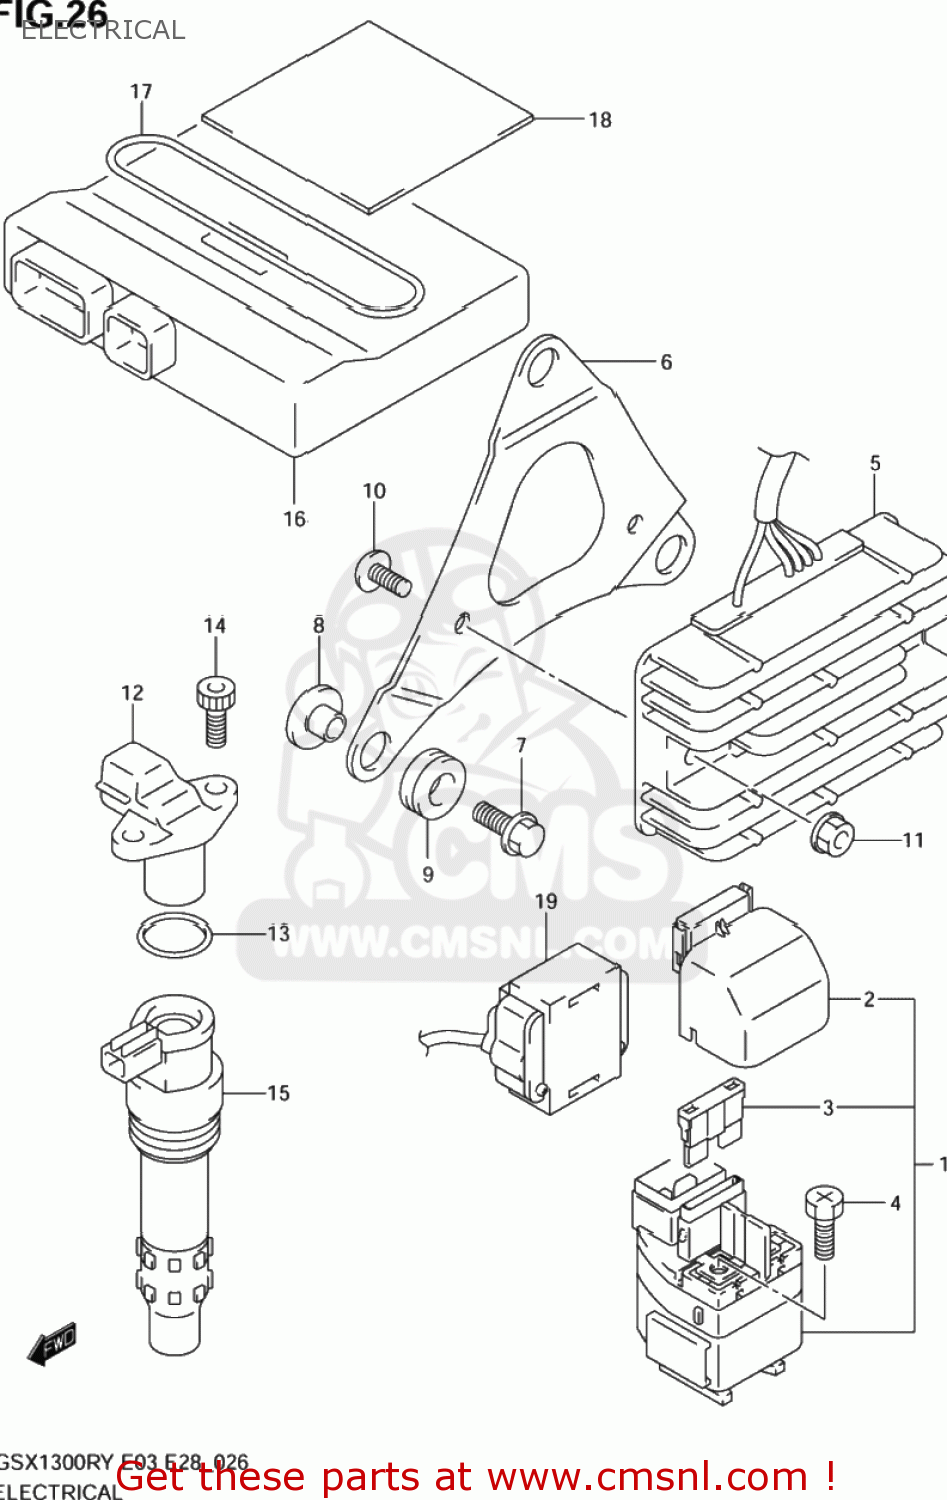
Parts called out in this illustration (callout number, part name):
1	RELAY ASSY,STARTING MOTOR
2	COVER,STARTER RELAY
3	FUSE(30A)
4	SCREW(6X8)
5	RECTIFIER ASY
6	BRACKET,RECTIFIER
7	BOLT(6X25)
8	WASHER
9	CUSHION
10	SCREW
11	NUT
12	SENSOR ASSY,CAM POSITION
13	PACKING (NAS)
14	BOLT,OIL FILLE
15	COIL ASSY,IGNITION
16	CONTROL UNIT,FI
17	BAND,BATTERY
18	PROTECTOR(40X40X16)
19	SENSOR ASSY,FUEL CUT
